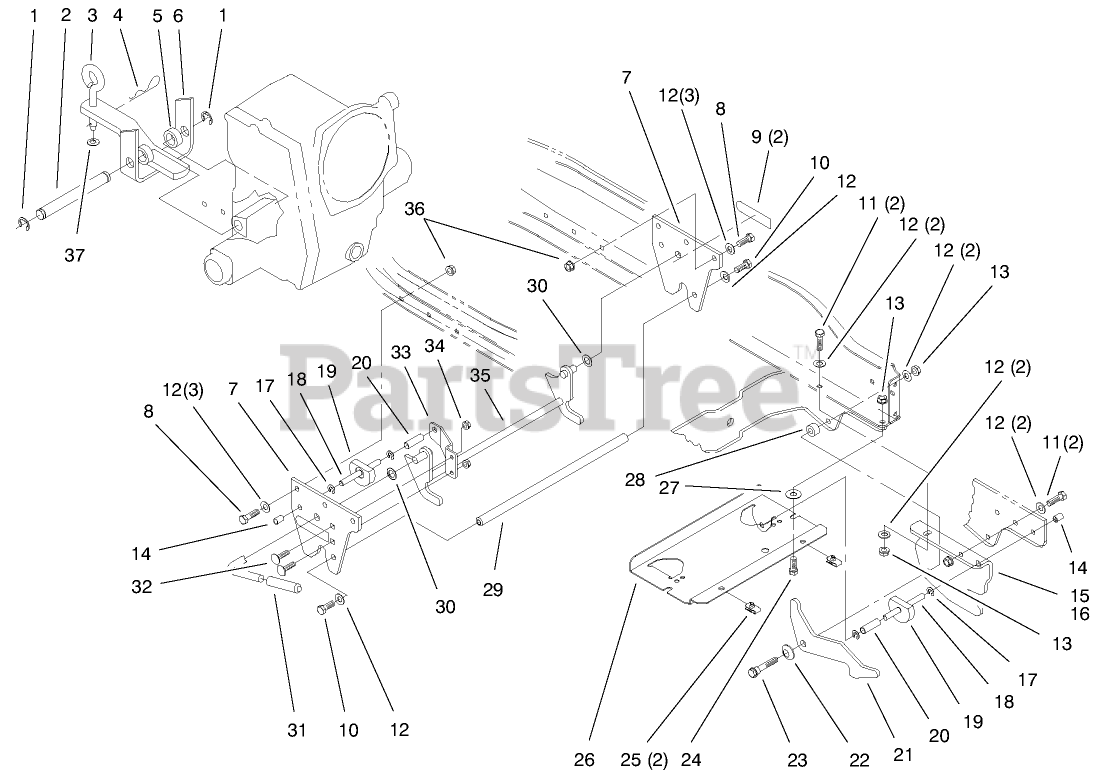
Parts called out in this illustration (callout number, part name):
1	E-RING
2	PIN-STATIONARY HITCH
3	PIN-TOOL
4	PIN-HAIR
5	SPACER
7	PLATE-HITCH
8	SCREW-HH
9	DECAL-ATTACH A MATIC
10	SCREW-HH, LOCK
11	SCREW-HH
12	WASHER-FLAT
13	NUT-LOCK, NI
14	CAP-ROD, PLUNGER
15	HANGER-RH
16	HANGER-LH
17	RING-RETAINING
18	ROD-LOCK
19	LOCK-LATCH
20	SPRING
21	LATCH-BOX, PULLEY
22	WASHER-SPRING
23	BOLT-SHOULDER
24	SCREW-HH
26	TRAY-BATTERY
27	WASHER-TOP THRUST
28	SPACER
29	ROD-SPACER
30	WASHER
31	GRIP
32	BOLT-CARR
33	BRACKET-ARM, MID
34	NUT-LOCK, NI
36	NUT-HEX
37	WASHER-FLAT
